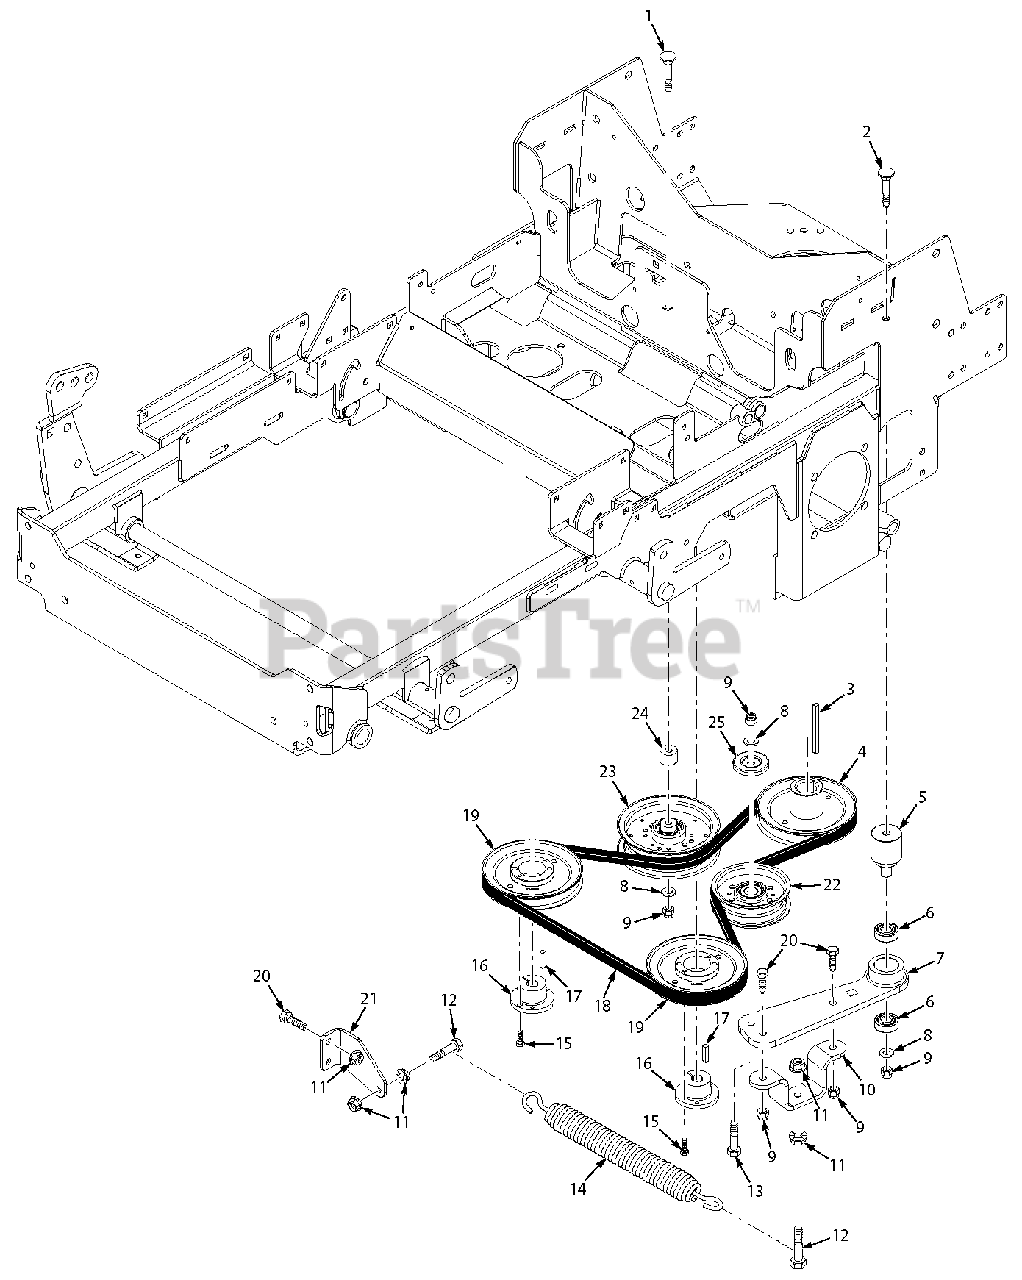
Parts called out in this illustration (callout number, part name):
1	Bolt, Carriage 3/8-16 x 3-1/4"
2	Bolt, Carriage 3/8-16 x 4"
3	Key, 1/4 x 1/4 x 3-1/2"
4	Pulley, 5.75" Dia. - 1.125 Bore
5	Pivot, Idler Arm
6	Bearing
7	Idler Arm Assembly
8	Flatwasher, 3/8-.391 x .938 x .105 HD
9	Nut, Elastic Stop 3/8-16
10	Mounting Bracket, Idler
11	Nut, Serrated Flange 3/8-16
12	Bolt, Hex Head 3/8-16 x 1-1/2"
13	Bolt, Hex Head 3/8-16 x 2-1/2"
14	Spring, Pump Drive
15	Bolt, Hex Head 1/4-20 x 1"
16	Hub, Tapered, 15mm Bore
17	Key, 5 x 5 x 25mm
18	Belt, Pump Drive (48"/52")
18	Belt, Pump Drive (61")
19	Pulley, 5.75" OD Taper Bore
20	Bolt, Hex Head 3/8-16 x 1-1/4"
21	Bracket, Spring Anchor
22	Pulley, 4" Dia. Idler
23	Pulley, 5" Dia. Idler
24	Spacer
25	Dust Shield
